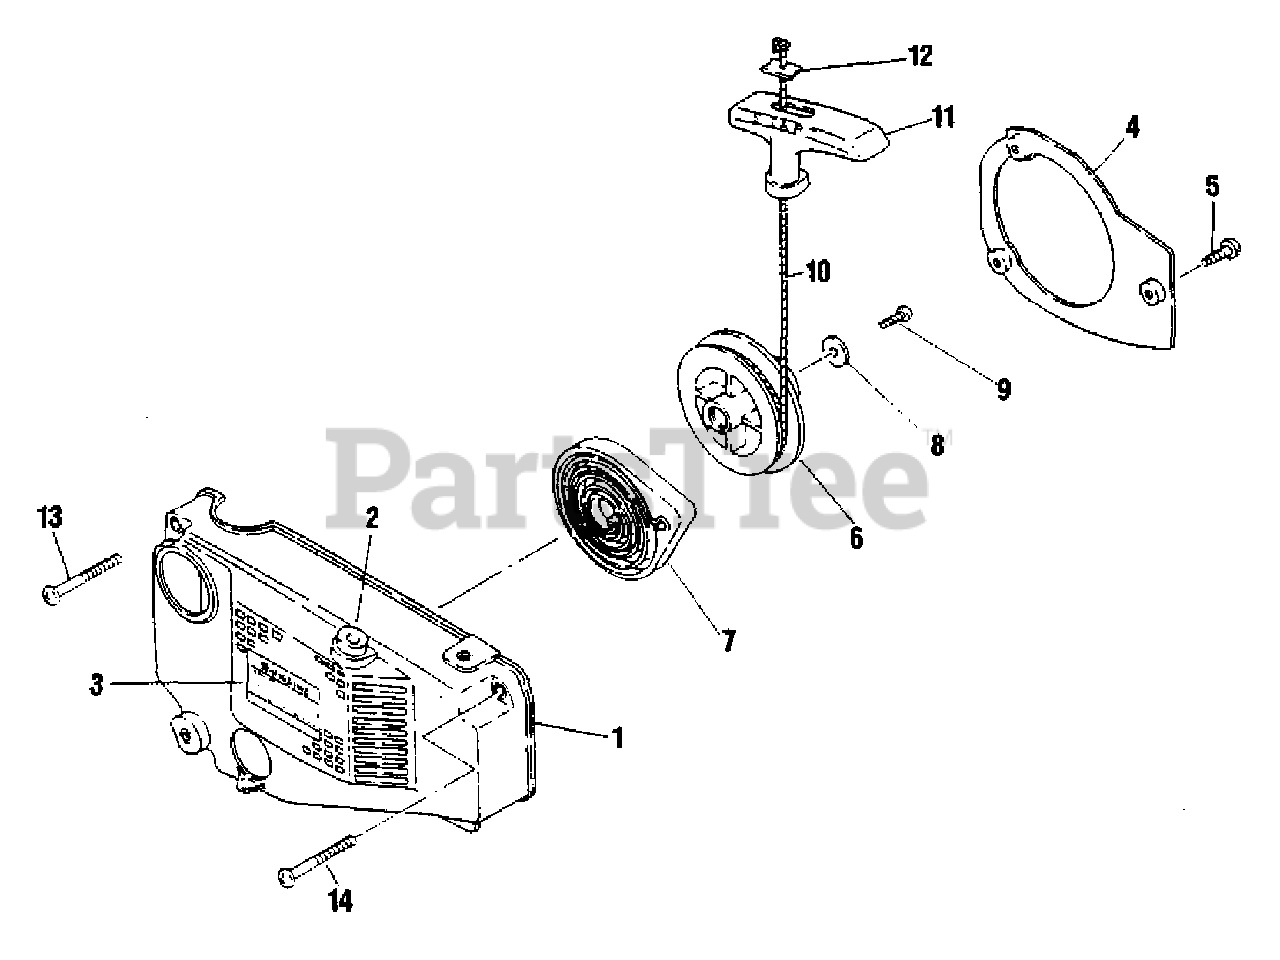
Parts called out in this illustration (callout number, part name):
1	CASE, STARTER
2	GUIDE
3	NAME PLATE
4	DEFLECTOR, AIR
5	SCREW
7	RECOIL SPRING
9	SCREW
11	GRIP, STARTER
12	RETAINER, ROPE
13	SCREW
14	SCREW M4×20
